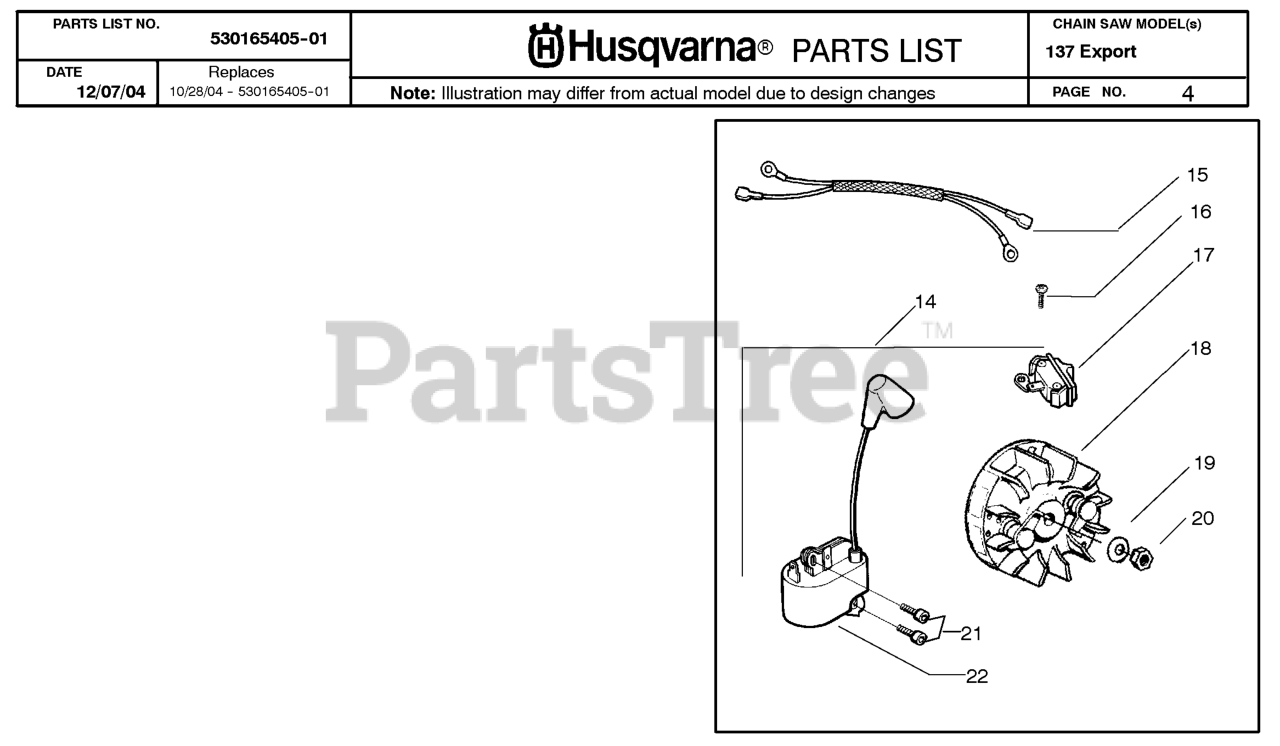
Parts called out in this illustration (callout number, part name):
14	Kit-EPS ignition
15	LEAD WIRE ASSY
17	SWITCH ON/OFF
18	FLYWHEEL ASSY
19	WASHER-FLYWHEEL
20	NUT-FLYWHEEL
21	SCREW,IGN MOD 36/41
22	IGNITION MODULE
